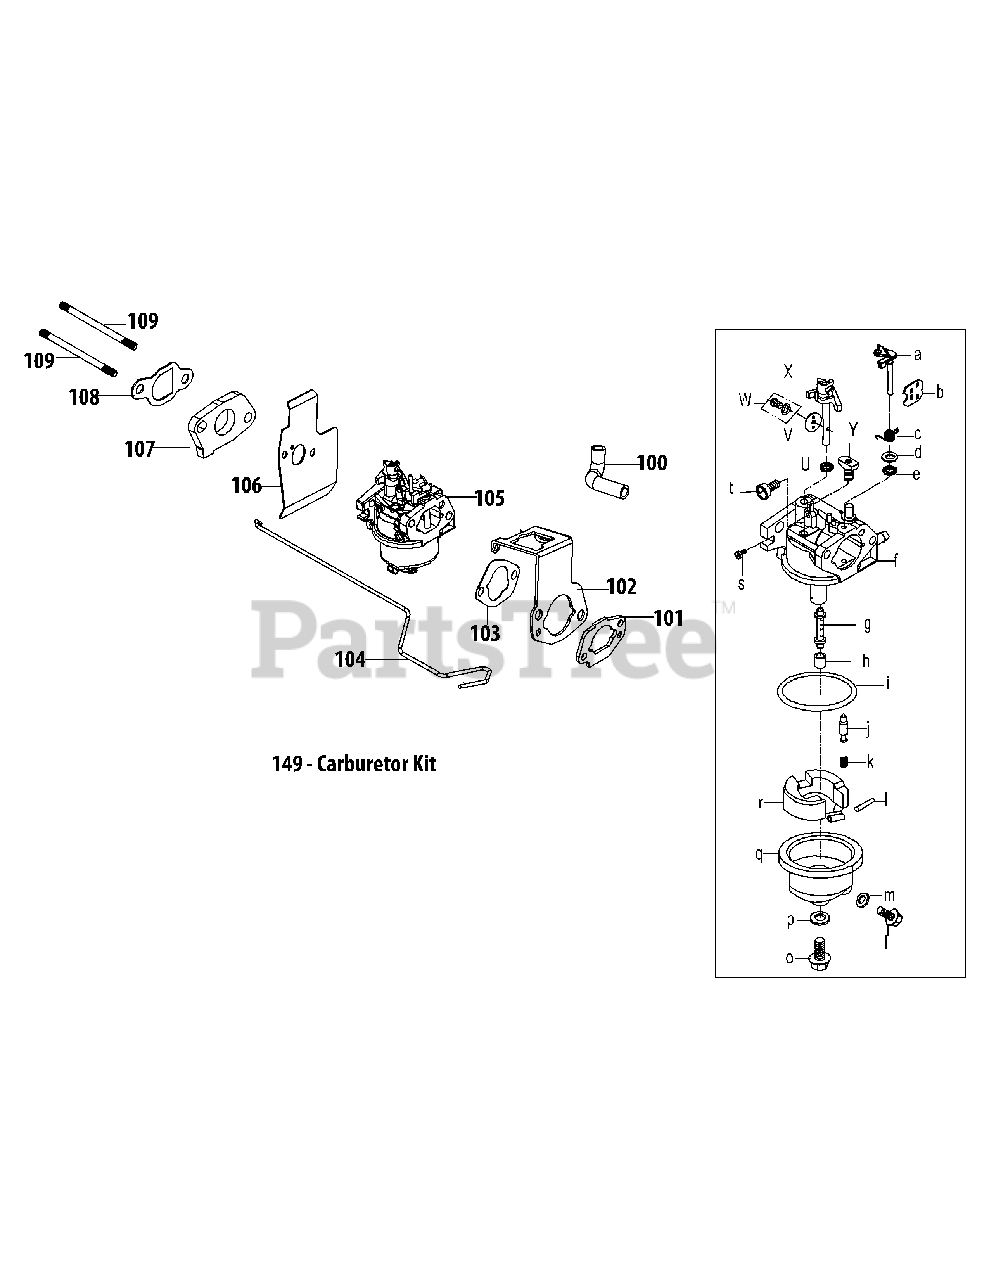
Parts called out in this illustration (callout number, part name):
100	Breather Hose
101	Air Filter Base Gasket
102	Temp Control Guide Bracket
103	Temp Control Guide Bracket Gasket
104	Temp Control Linkage
105	Carburetor Assembly
106	Carburetor Gasket
107	Carburetor Insulator
108	Carburetor Insulator Gasket
109	Carb Stud M6×87
149	Carb Kit (d,e,f,g,h,j,m,n,o,p)
